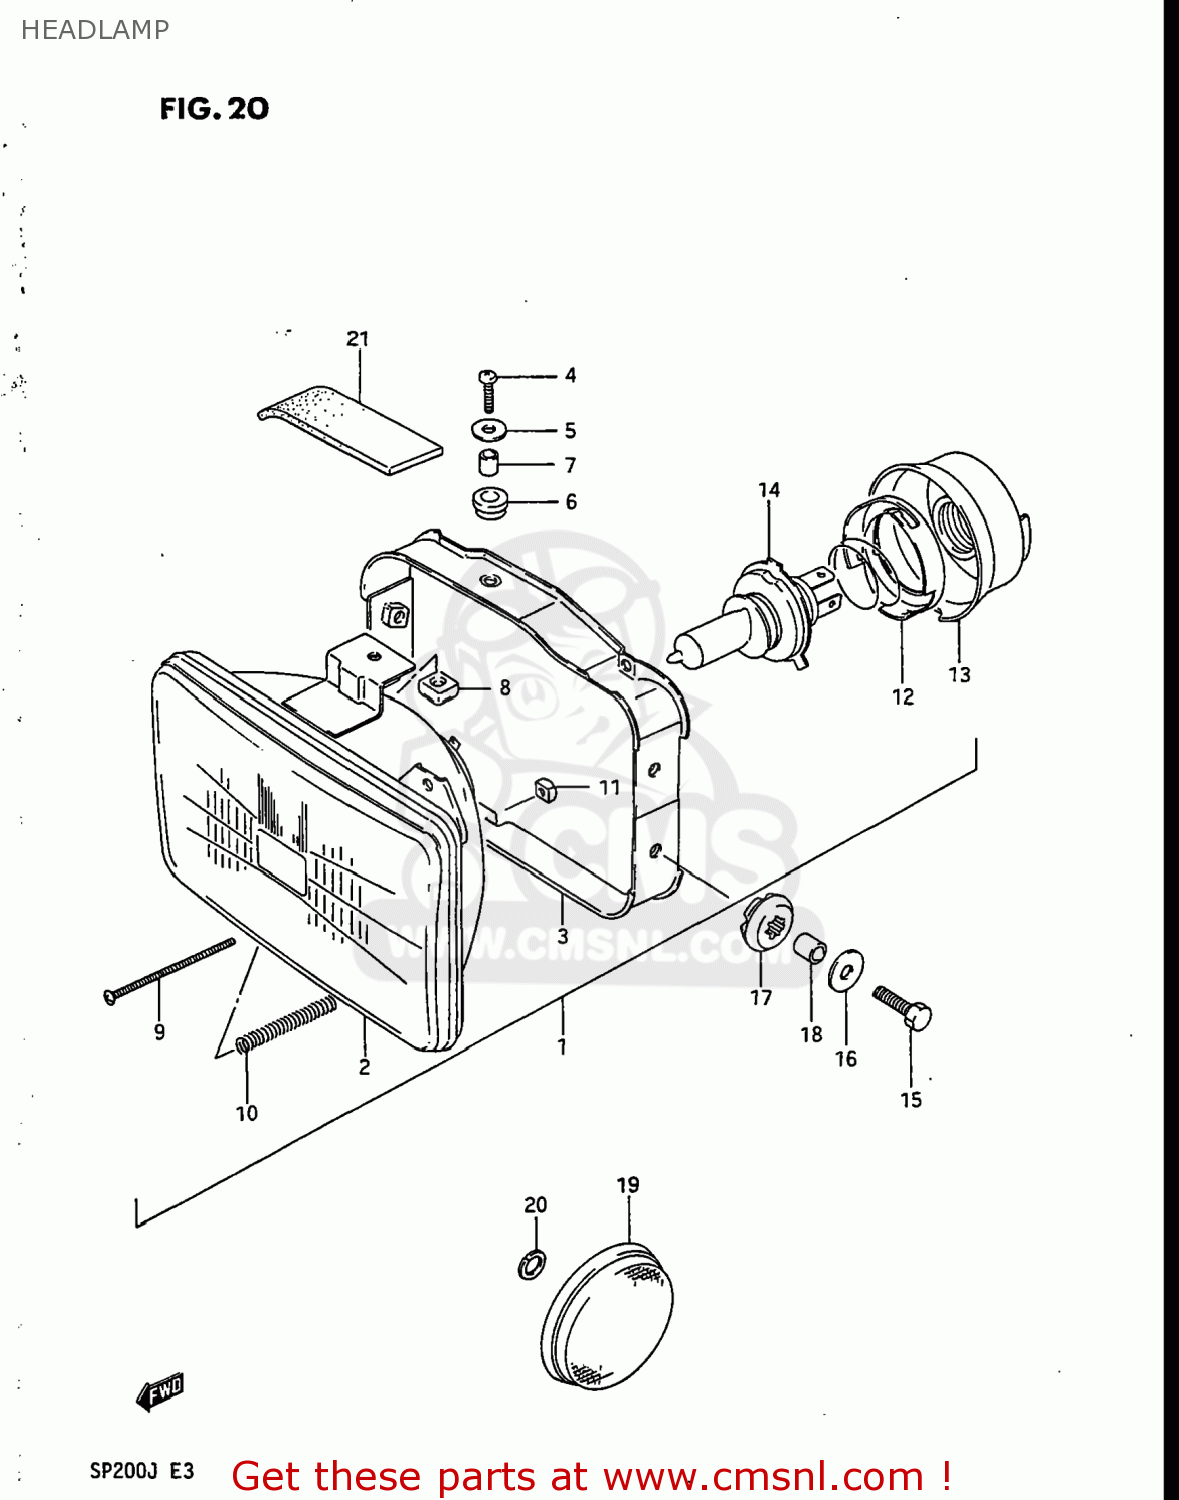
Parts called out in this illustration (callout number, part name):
1	HEADLAMP ASSEMBLY
2	LAMP UNIT
3	HOUSING
4	SCREW 5X20
5	WASHER
6	CUSHION
7	SPACER
8	NUT
9	SCREW,HEADLAMP ADJUST
10	SPRING
11	NUT
12	HOLDER,BULB
13	COVER,SOCKET
14	BULB 12V 45/45W BF130-0
15	BOLT
16	WASHER (6.5X20X1.2)
17	CUSHION
18	SPACER (6.1X9X9)
19	REFLEX REFLECTOR,FR
20	LOCK WASHER
21	CUSHION
